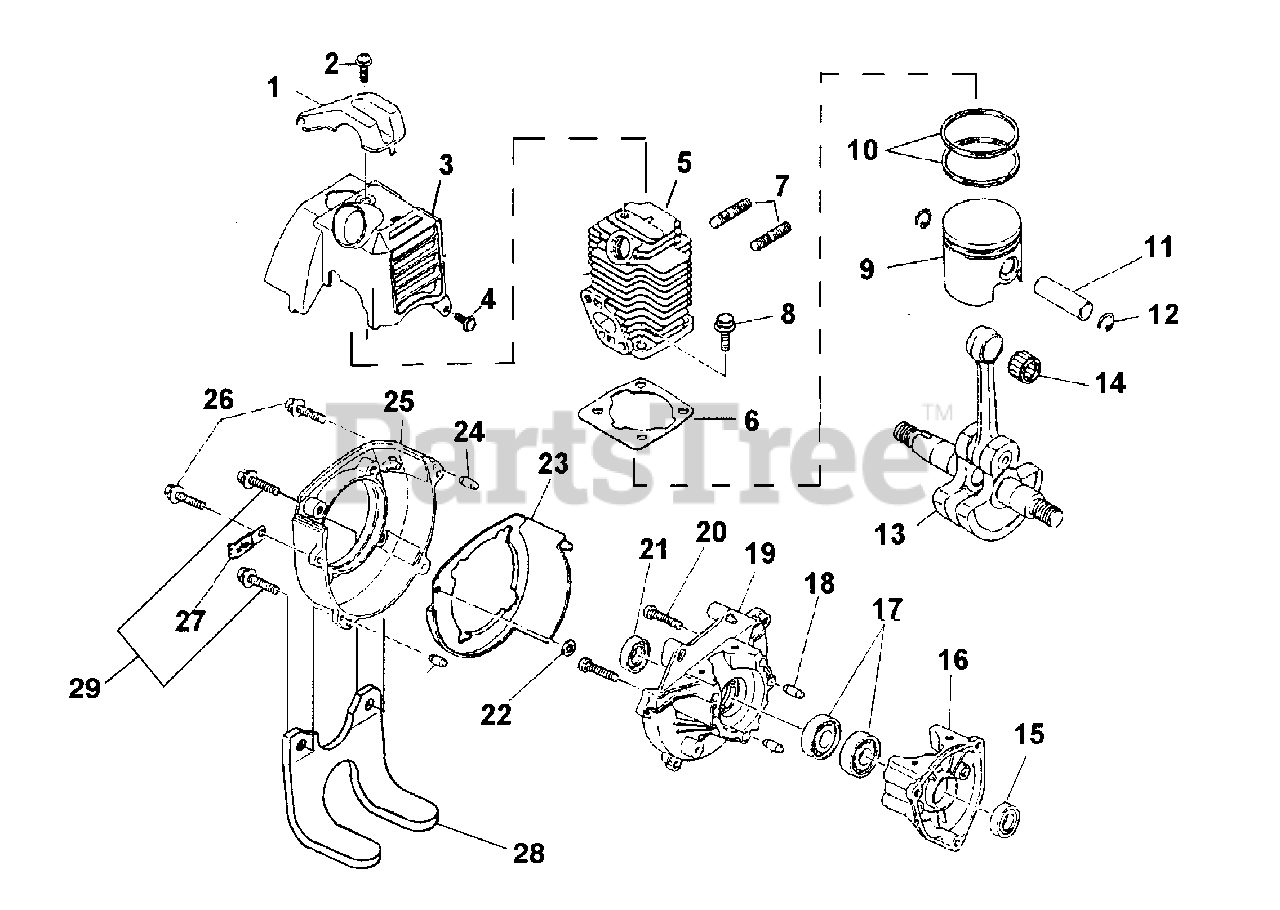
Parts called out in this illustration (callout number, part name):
1	GUARD, PLUG
2	SCREW 8 WASHER
3	COVER, TOP
4	SCREW 8 WASHER
5	CYLINDER ASSY. (26cc)
6	GASKET, CYLINDER
8	SCREW & WASHER
9	PISTON ASSY.
10	RING, PISTON
11	PIN, PISTON
12	CLIP, PISTON
13	CRANKSHAFT ASSY.
15	OIL SEAL
16	CASE, STARTER
18	PIN, DOWEL
19	CASE, DRIVE
20	SCREW
21	OIL SEAL
24	PIN, DOWEL
25	CASE, FAN
26	BOLT 8 WASHER
28	ENGINE STOP
29	SCREW (M5 X 20)
